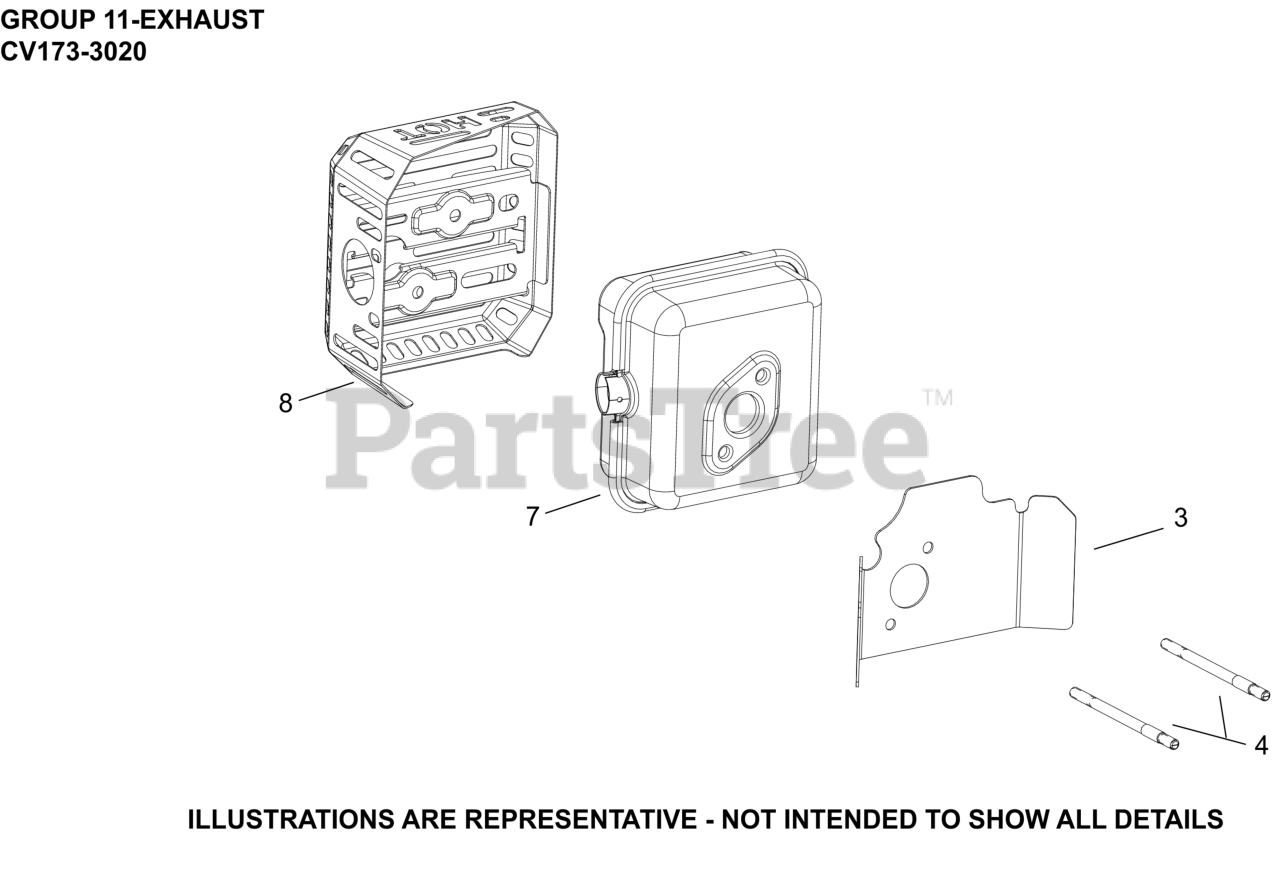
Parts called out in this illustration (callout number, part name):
3	GASKET, MUFFLER (HEAT DEFLECTOR)
4	STUD, EXHAUST (M6)
7	MUFFLER, ASSEMBLY
8	GUARD, MUFFLER ASSEMBLY
